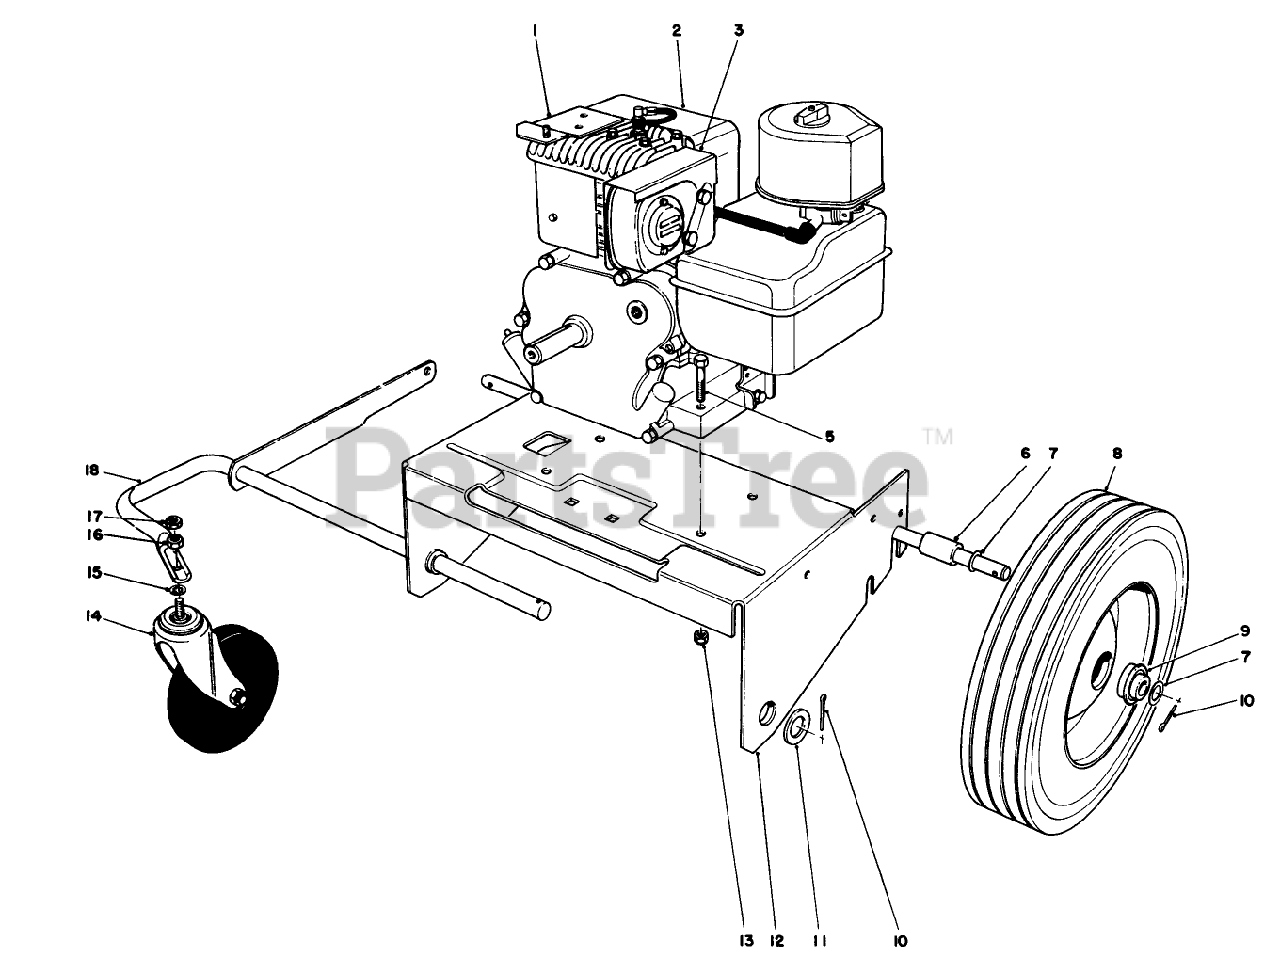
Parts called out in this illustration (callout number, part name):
1	MTG BRKT WA *B
2	Engine
3	HEAT SHIELD
5	SCREW-HH
6	SPACER-AXLE
7	WASHER
8	WHEEL
9	BEARING
10	PIN-COTTER
11	WASHER-FLAT
13	NUT-LOCK, NI
14	CASTER
15	WASHER-LOCK/INT
16	NUT-HH
17	NUT-LOCK, NI
